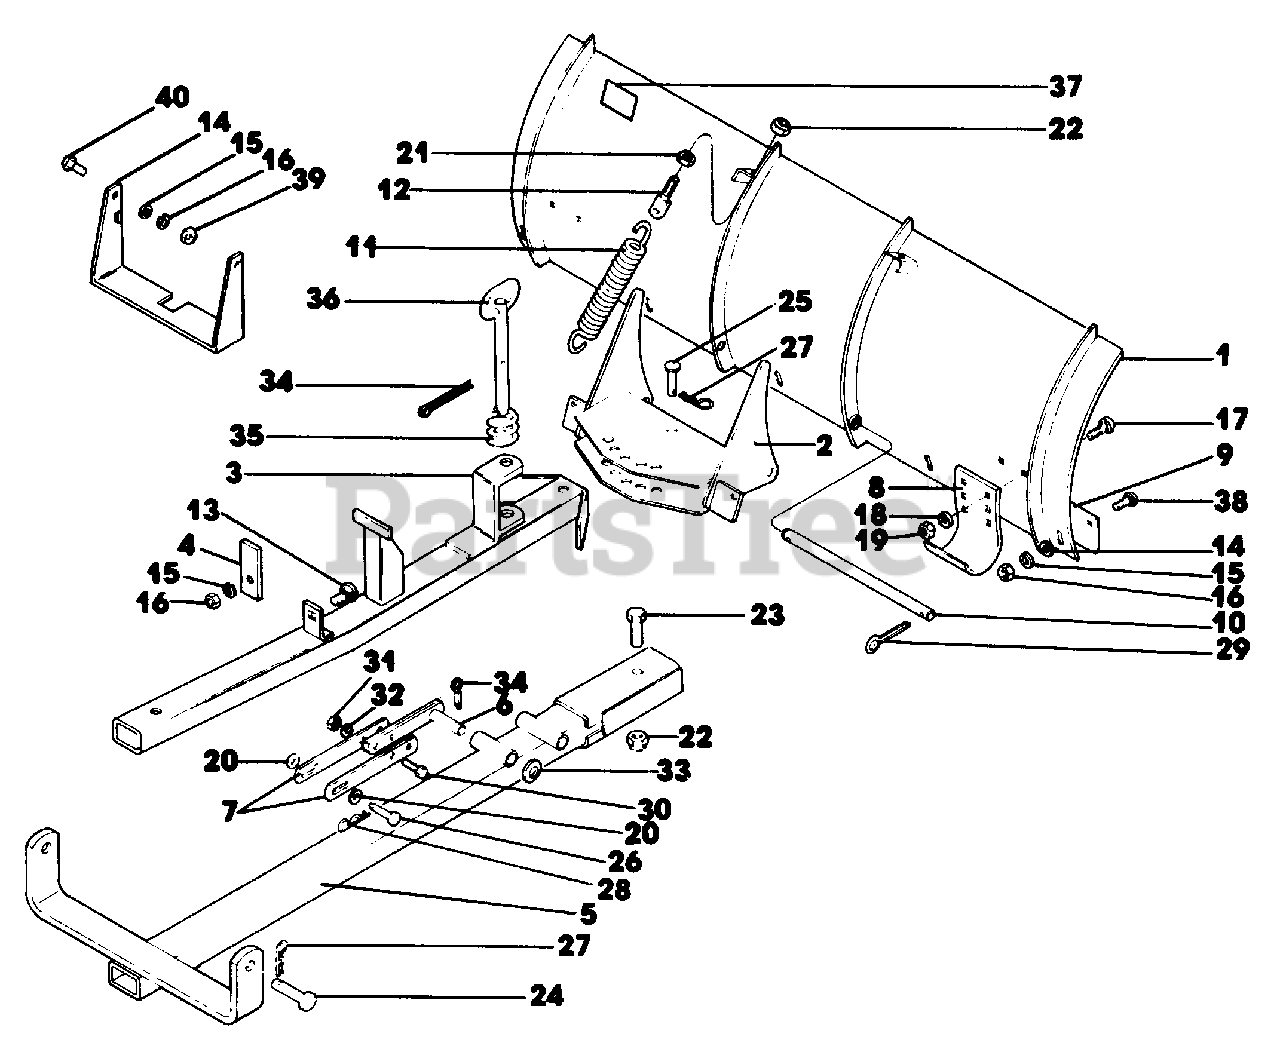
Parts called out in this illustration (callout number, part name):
1	Dozer Blade Assembly w/Decal
2	Trip Plate Assembly
3	Front Frame Assembly
4	Frame Stop
5	Rear Frame Assembly
6	Lift Link Assembly
7	Reversing Link
8	Shoe
9	Scraper Blade
10	Trip Pin
11	Spring
12	Spring Adjuster Bolt
13	Bolt, Wafer Hd. Short Neck
14	Washer, Flat SAE 5/16 Plated
15	Washer, Spring Lock 5/16 Plated
16	Nut, Hex 5/16-18 Plated
17	Bolt, Carriage 3/8-16 x 1" Plated
18	Washer, Lock Plated
19	Nut, Hex 3/8-16 Plated
20	Washer, Flat SAE 7/16 Plated
21	Nut, Hex Jam 1/2-13 Plated
22	Nut, Hex Cone Lock 1/2-13 Plated
23	Cap Screw, Hex Hd. 1/2-13 x 2-1/2" Plated, Grade 5
24	Clevis Pin
25	Clevis Pin
26	Clevis Pin
27	Spring Clip
28	Spring Clip
29	Pin, Cotter 3/16 x 1-1/2 Plated
30	Cap Screw, Hex Hd. 7/16-14 x 1-1/2" Plated, Grade 5
31	Nut, Hex 7/16-14 Plated
32	Washer, Lock 7/16 Plated
33	Washer, Flat SAE 3/4 Plated
34	Pin, Cotter 1-1/4" Plated
35	Spring
36	Hitch Pin Assembly
37	Safety Decal
38	Bolt Carriage 5/16-18 x 1" Plated
39	Stabilizer Saddle Assembly
40	Cap Screw, Hex Hd. 5/16-18 x 1" Plated, Grade 5
